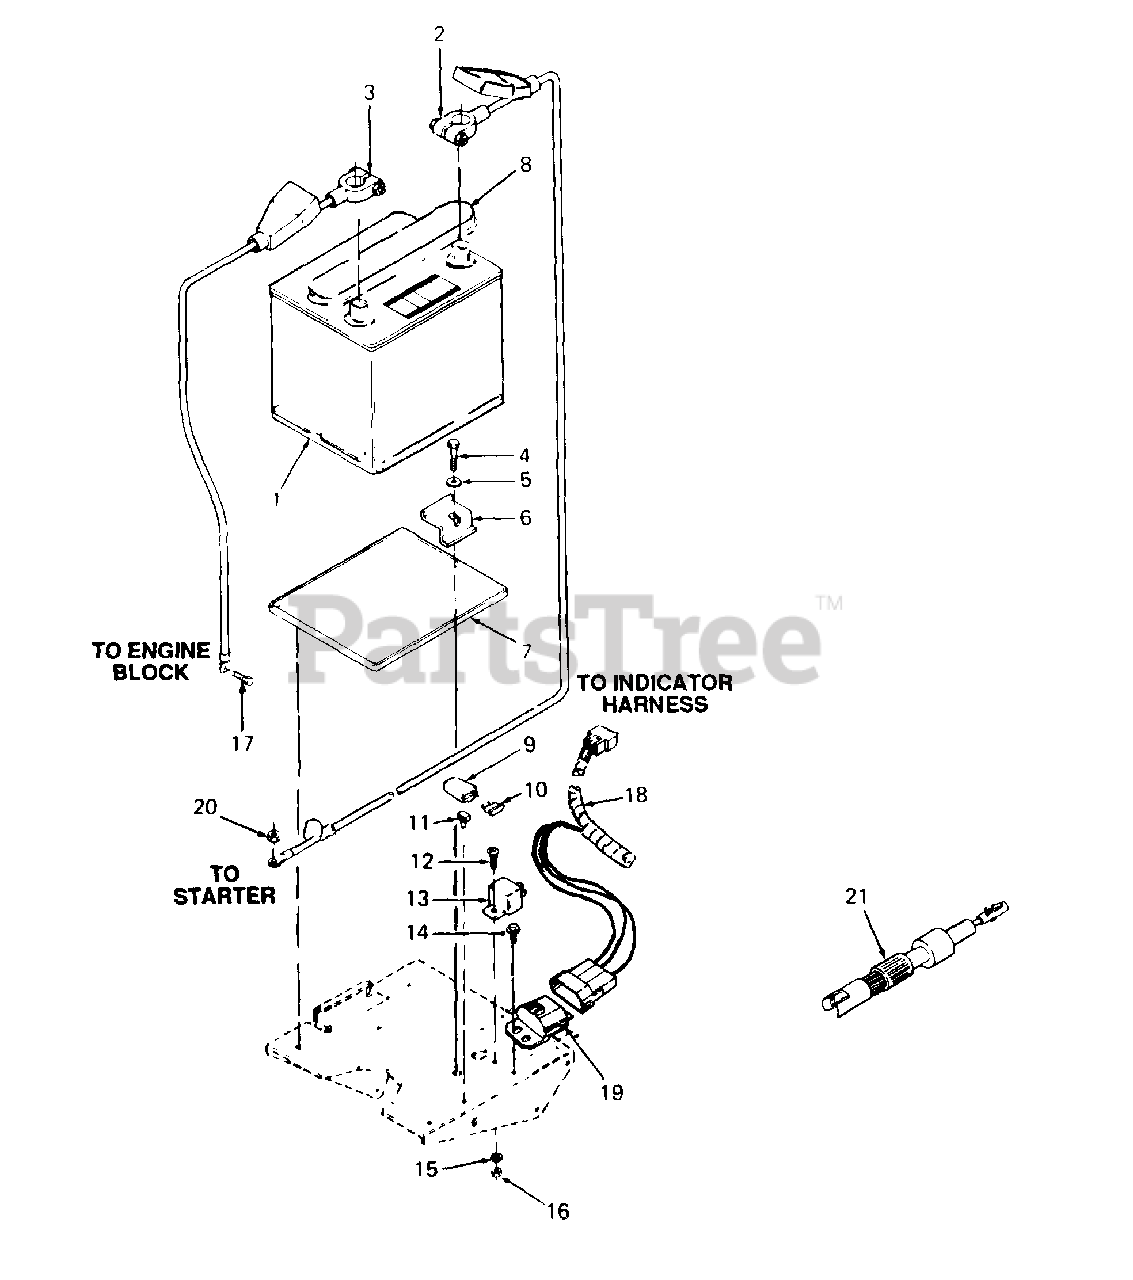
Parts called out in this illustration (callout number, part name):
1	Battery
2	Cable, Positive Battery
3	Cable, Negative Battery
4	Screw, Hex Cap, 5/16-18 x 1.38 Lg
5	Washer, Flat, .34 x .68 x .062 Thk
8	Cap, Battery Vent
9	Holder, Fuse
10	Fuse, 20 Amp
11	Clip, Fuse Holder Mtg
12	Screw, Truss Mach, #10-24 x .50 Lg
13	Relay
14	Screw, Hex Wash Hd TT, 1/4-20 x .50 Lg
15	Washer, Lock, #10
16	Nut, Hex, #10-24
17	Screw, Hex Cap, M8-1.25 x 14 MM Lg
18	Main Harness
19	Module, Voltage Sensor
20	Nut, Hex, M8-1.25 GR8.8
21	Diode Assy
